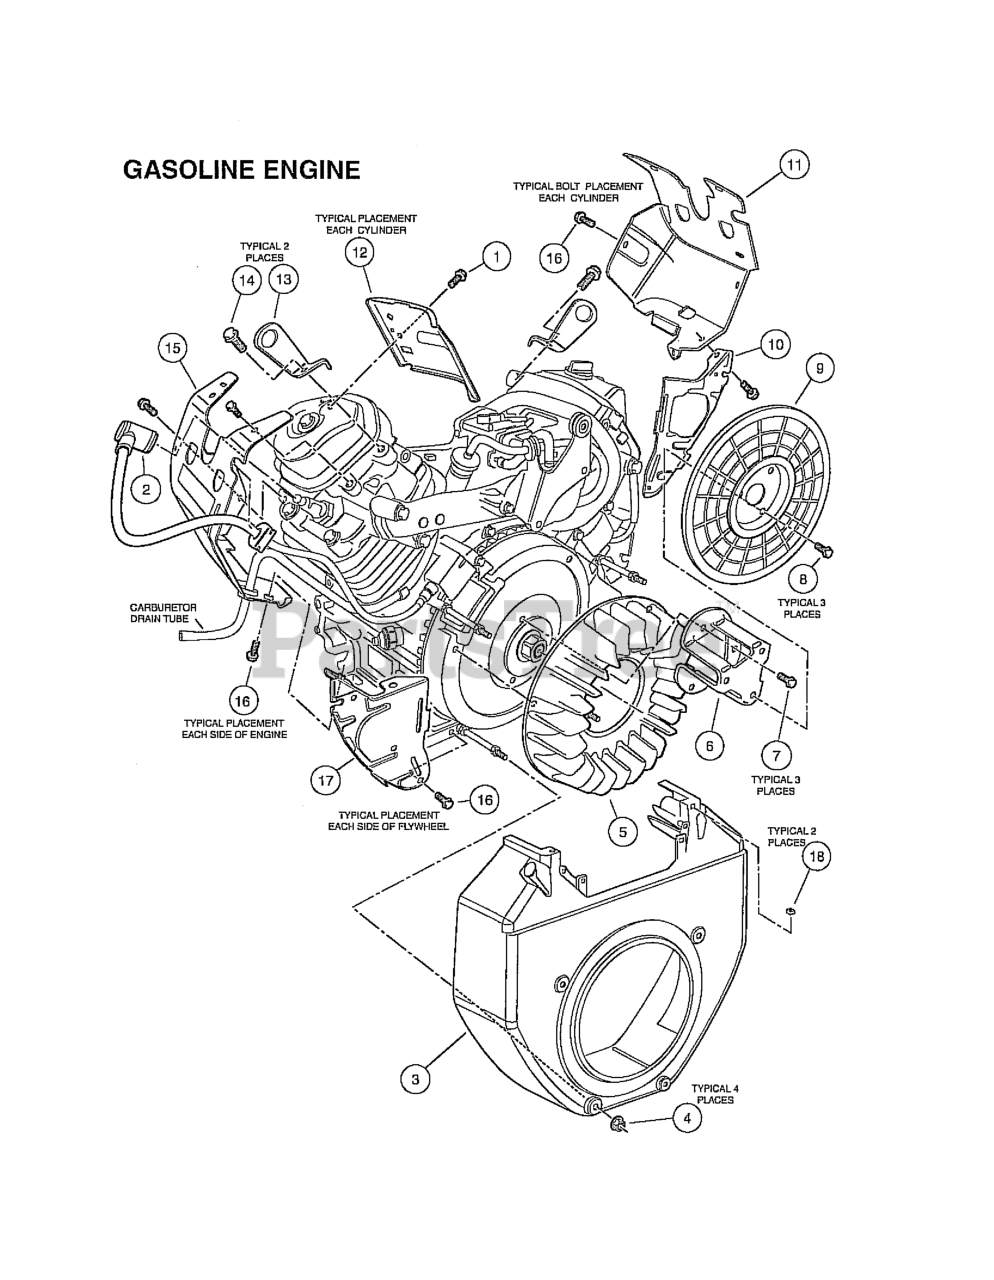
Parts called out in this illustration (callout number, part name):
1	BOLT, FLANGE, M6 X 11 X 4
3	COVER, FAN, BRIGHT RED
4	NUT, FLANGE, M6
5	FAN, COOLING
6	HOLDER, SCREEN GRID
7	BOLT, FLANGE, M8 X 1.25 X 16
8	BOLT, FLANGE, M6 X 1 X 12
9	GRID, SCREEN, P.T.O.
10	PLATE, R SIDE
12	SHROUD, HEAD
13	HANGER, ENGINE
14	BOLT, FLANGE, M8 X 1.25 X 20
16	BOLT, FLANGE, M6 X 1 X 12, CT2
17	PLATE, L SIDE
